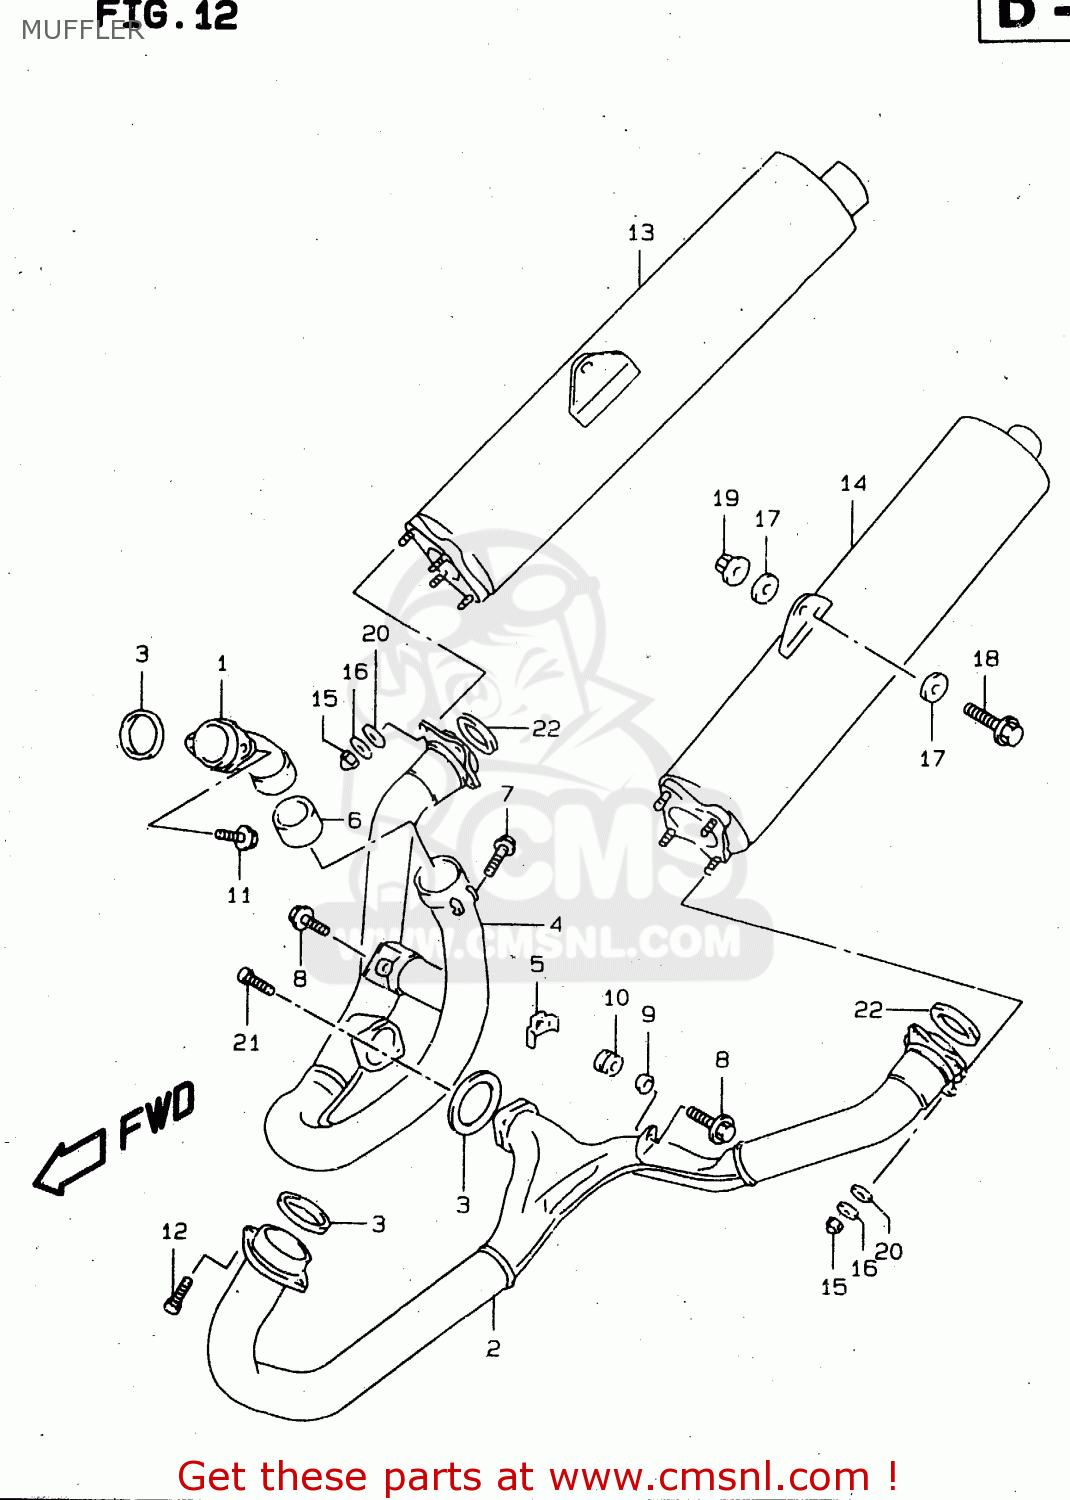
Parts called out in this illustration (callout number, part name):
1	PIPE,EXHAUST,R
2	PIPE,EXHAUST,L
3	GASKET,EXHAUST PIPE (NAS)
4	PIPE,EXHAUST JOINT,R
5	SPROCKET,EXHAUST,L
6	CONNECTOR,EXHAUST,R
7	BOLT
8	BOLT 8X45
9	SPACER(8.6X12X24.2)
10	CUSHION
11	BOLT
12	BOLT
13	BODY,MUFFLER,R
14	BODY,MUFFLER,L
15	NUT
16	WASHER(8.5X18X1.6)
17	WASHER (8.5X24X1.6)
18	BOLT
19	NUT
20	O RING(D:1.9,ID:7.8)
21	BOLT,EXH MANF
22	GASKET,MUFFLER JOINT (NAS)
